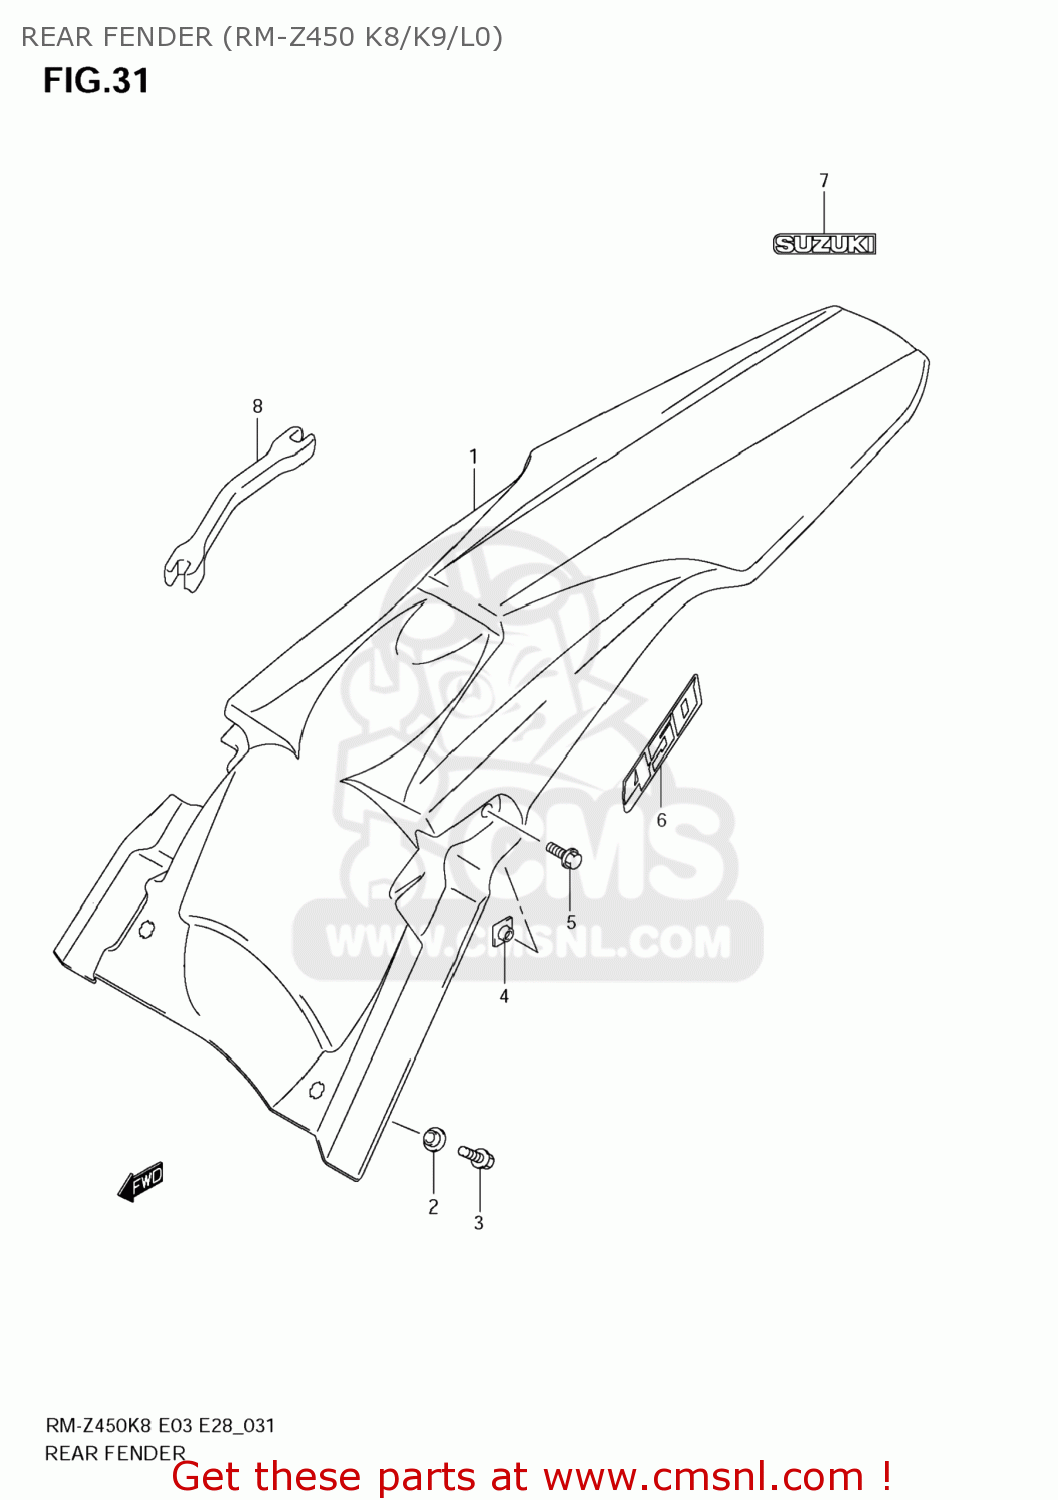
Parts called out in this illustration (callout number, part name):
1	FENDER,RR
2	WASHER,FR FENDER
3	BOLT
4	NUT
5	BOLT(6X16)
6	EMBLEM,RR FENDER
7	EMBLEM,SUZUKI
8	OPEN SPANNER(6.4X6.8)
